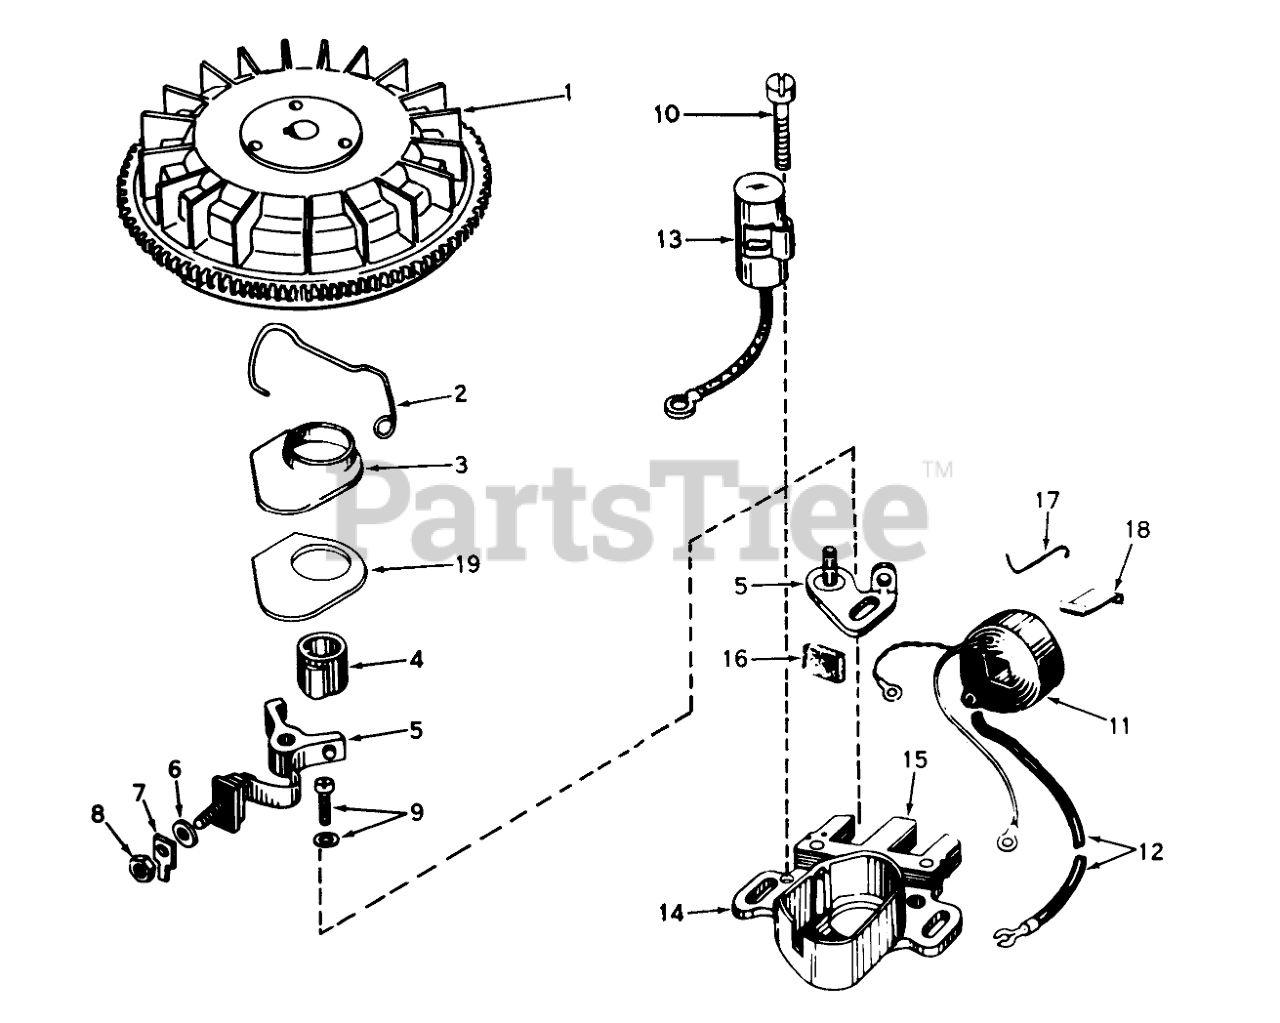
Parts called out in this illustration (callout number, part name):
1	FIywheel
2	Spring Breaker Box
3	Cover, Dust
4	Cam-Breaker
5	Breaker Assy.
7	Terminal
9	Breaker Screw
10	Condenser Screw
11	Coil Assy. (Incl. No. 12)
12	Wire, Lead
13	Condenser
14	Core & Plate
15	Stator Assy. (Incl. Nos. 5 thru 14, 16, 17 & 18)
16	Felt,Cam Wiper
17	Clip, Coil
18	Spring Coil Wedge
19	Gasket Dust Cover
